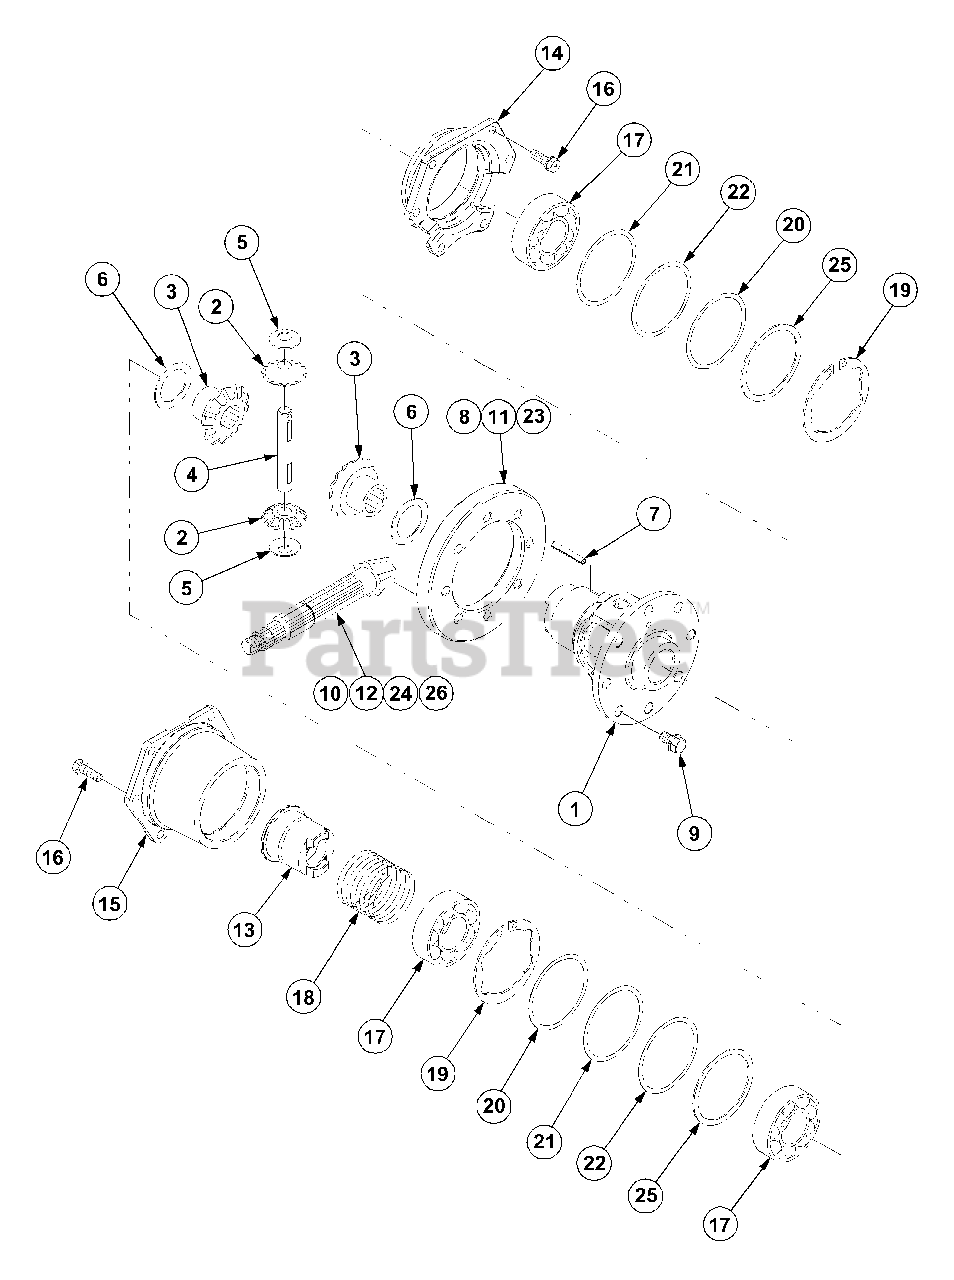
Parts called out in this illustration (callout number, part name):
5	Washer,Thrust
6	Washer,Thrust
16	Bolt,w/Washer
